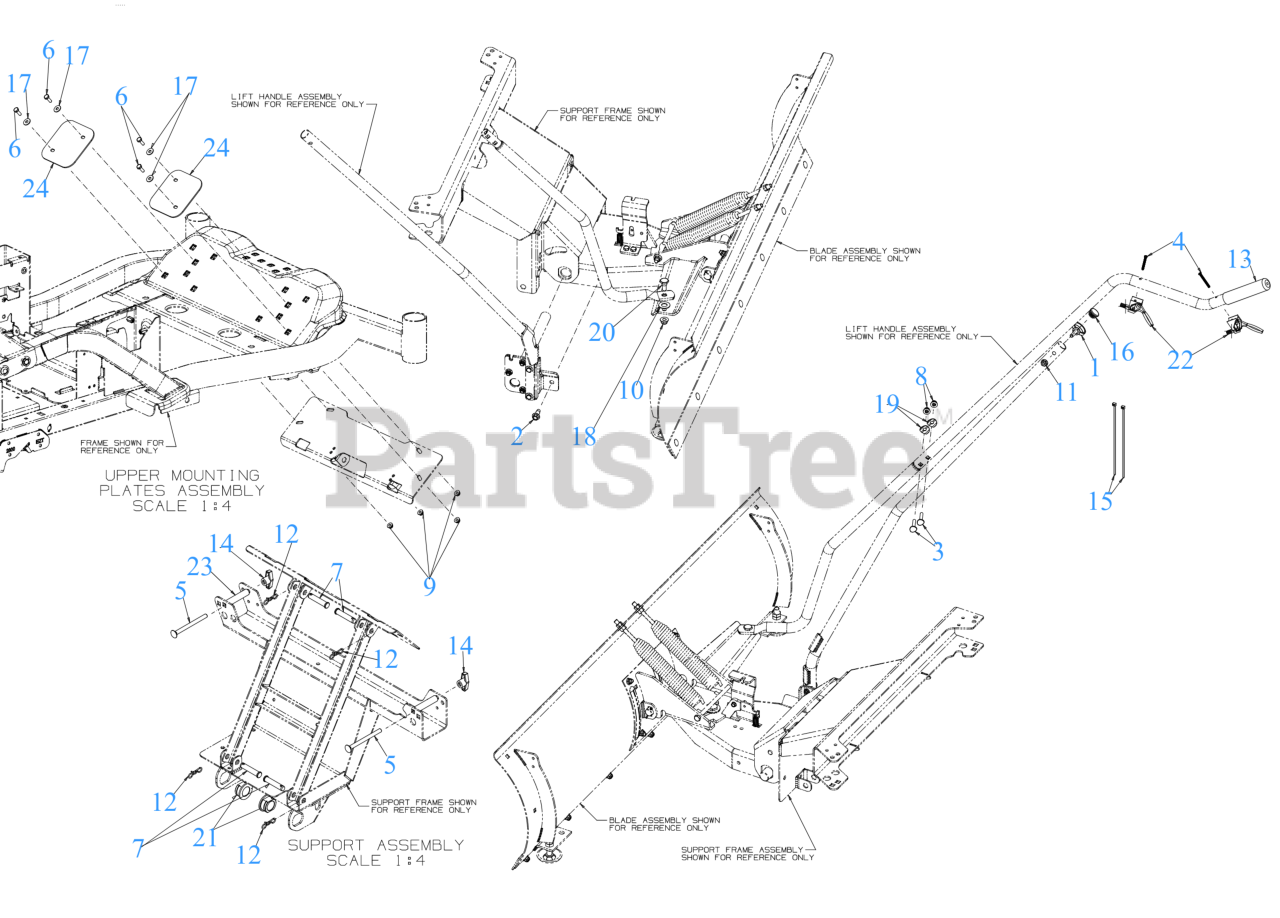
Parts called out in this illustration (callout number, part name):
2	SCREW 3/8-16 x 1
3	CARRIAGE BOLT 5/16-18 x 1.5
4	SCREW #10-24 x 1.75
5	CARRIAGE BOLT 3/8-16 x 4.25 GR5
6	SCREW 1/4-20X.75 GR5
7	CLEVIS PIN .50 x 2.5
8	FLANGE LOCK NUT 5/16-18
9	FLANGE LOCK NUT
11	HEX FLANGE NUT
12	BOW TIE COTTER PIN
14	WING KNOB 3/8-16
15	TIE CABLE 8.5 LG
17	FLAT WASHER .28 ID x .74 OD x .063
18	TEFLON WASHER .570x1.120x.062
19	SADDLE WASHER
20	SHOULDER SCREW .498 DIA x .340
21	FLANGE BEARING
22	BLADE RELEASE CABLE
23	SPACER .625 x 4.06 x 2.87
24	TOP MOUNT PLATE
